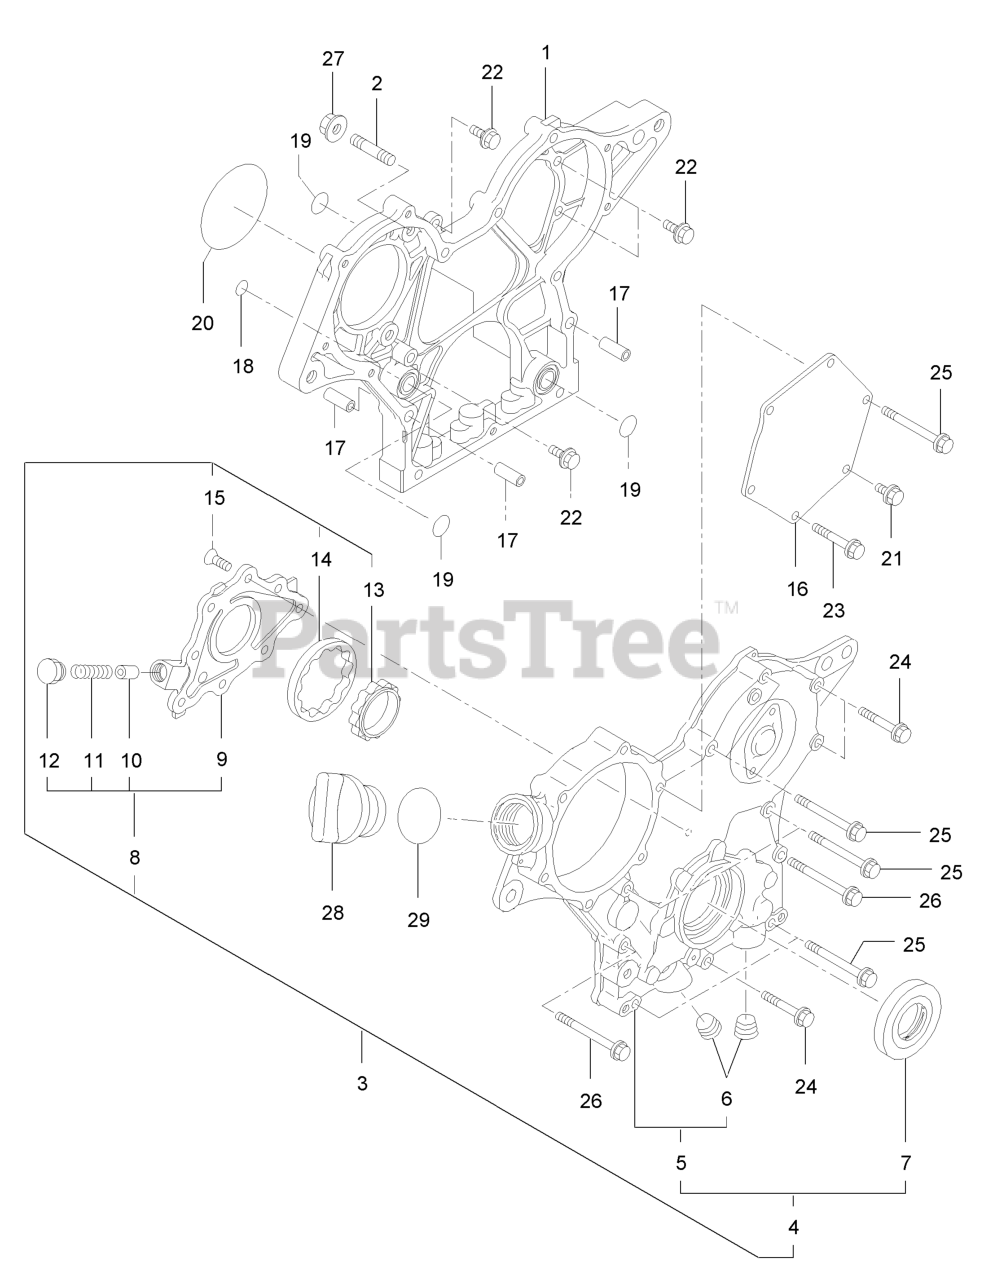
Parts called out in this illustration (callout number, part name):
1	Case-Gear
2	Bolt-Stud
3	Cover ASM-Gear Case
4	Cover Assy-Gear Case
5	Cover-Gear Case
7	Seal-Oil
8	Cover ASM
9	Cover-Pump
10	Valve-Relief
13	Rotor-Inner
14	Rotor-Outer
16	Cover-Pump
17	Pipe-Dowel
28	Cover-Filler
